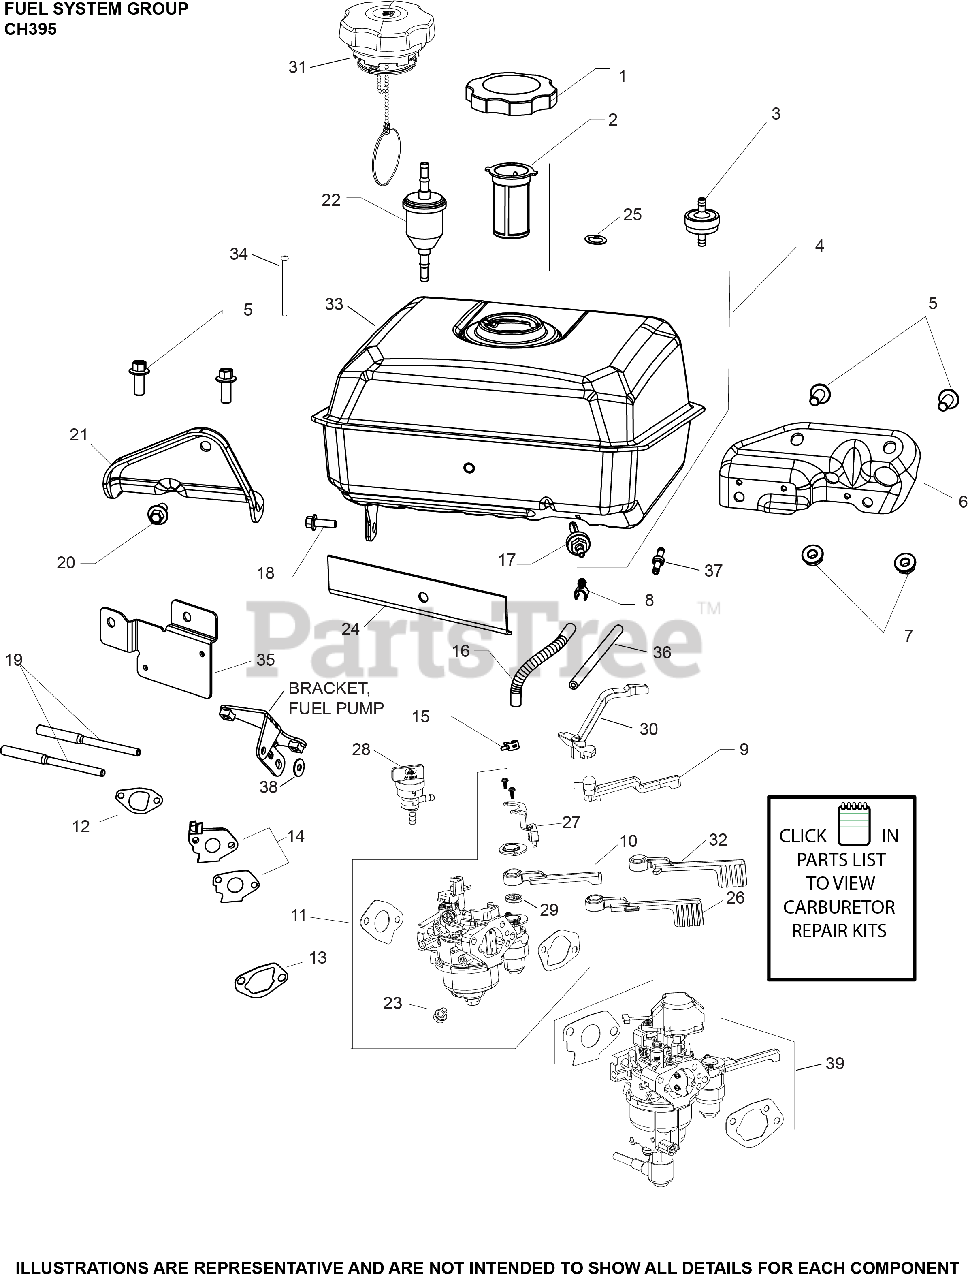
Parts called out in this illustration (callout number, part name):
5	SCREW, M8 X 20
14	INSULATOR AND GASKET KIT
15	CLAMP, FUEL LINE
16	LINE, FUEL (10"-CUT TO LENGTH)
19	STUD, INTAKE
22	FILTR,FUEL 75 MICRON (GRAVTY FEED)
28	VALVE, FUEL SHUTOFF
39	KIT, CARBURETOR COMPLETE
NI	KIT, HIGH ALTITUDE (4,000-8,000 FT)
NI	KIT, HIGH ALTITUDE (ABOVE 8,000 FT.)
NI	KIT, CARBURETOR REPAIR
